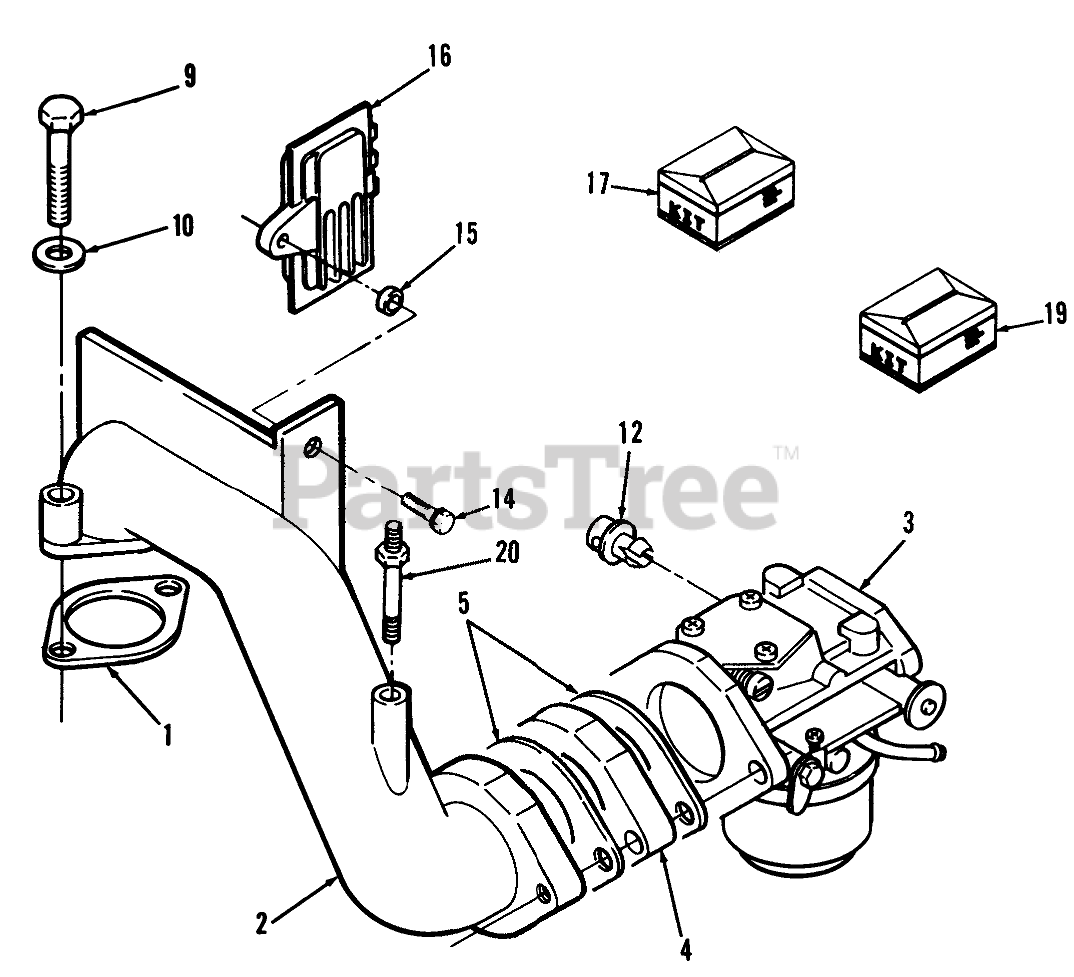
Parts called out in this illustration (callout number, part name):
1	Gasket
2	Elbow-Intake
3	CARBURETOR
4	INSULATOR
5	Gasket
9	SCR-HHC (M8X50)
10	WASHER-FLAT (M8)
12	Clip
14	SCHWH 1/4-20X 7/8 SB
15	Bushing
16	Regulator
17	Regulator
19	CARB-REBUILD KIT
